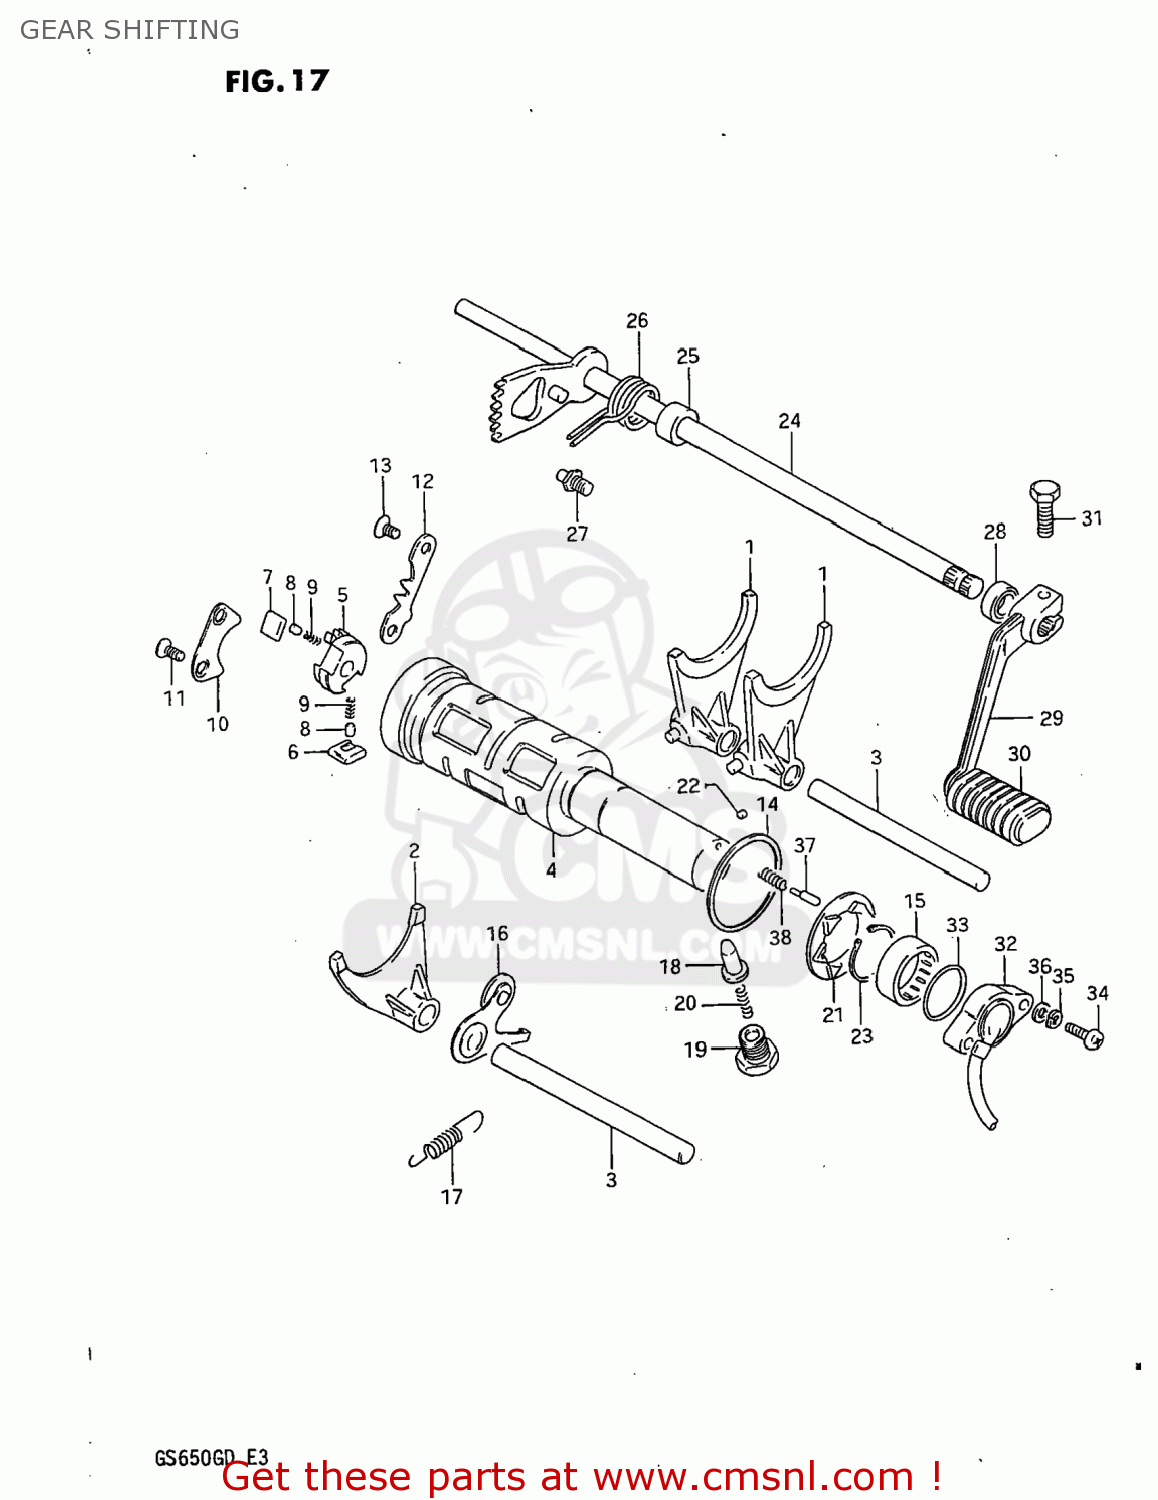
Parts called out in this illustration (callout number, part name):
1	FORK,GEAR SHIFT NO.1
2	FORK,GEAR SHIFT NO.3
3	SHAFT,GEAR SHIFT FORK
4	CAM,GEAR SHIFT
5	RETAINER,GEAR SHIFT CAM
6	PAWL,GEAR SHIFT NO.1
7	PAWL,GEAR SHIFT NO.2
8	PIN(5X8)
9	SPRING
10	LIFTER,GEAR SHIFT PAWL
11	SCREW
12	GUIDE,GEAR SHIFT
13	SCREW
14	WASHER(40X45X1)
15	BEARING(25X32X12)
16	STOPPER,GEAR SHIFTING
17	SPRING
18	STOPPER,GEAR SHIFT CAM NO.2
19	HOLDER,GEAR SHIFT CAM STOP SPR
20	SPRING
21	PLATE,GEAR SHIFT CAM STOPPER
22	PIN 4X6
23	CIRCLIP,25MM
24	SHAFT,GEAR SHIFT
25	SPACER(12X20X15.3)
26	SPRING
27	STOPPER,GEAR SHIFT CAM
28	OIL SEAL
29	LEVER ASSEMBLY,GEAR SHIFTING
30	RUBBER,PEDAL
31	BOLT
32	TERMINAL BASE ASSY,GEAR SHIFT
33	O-RING (D:2.4 ID:26.2)
34	SCREW 5X20
35	LOCK WASHER
36	WASHER
37	PIN(5X15.5)
38	SPRING
